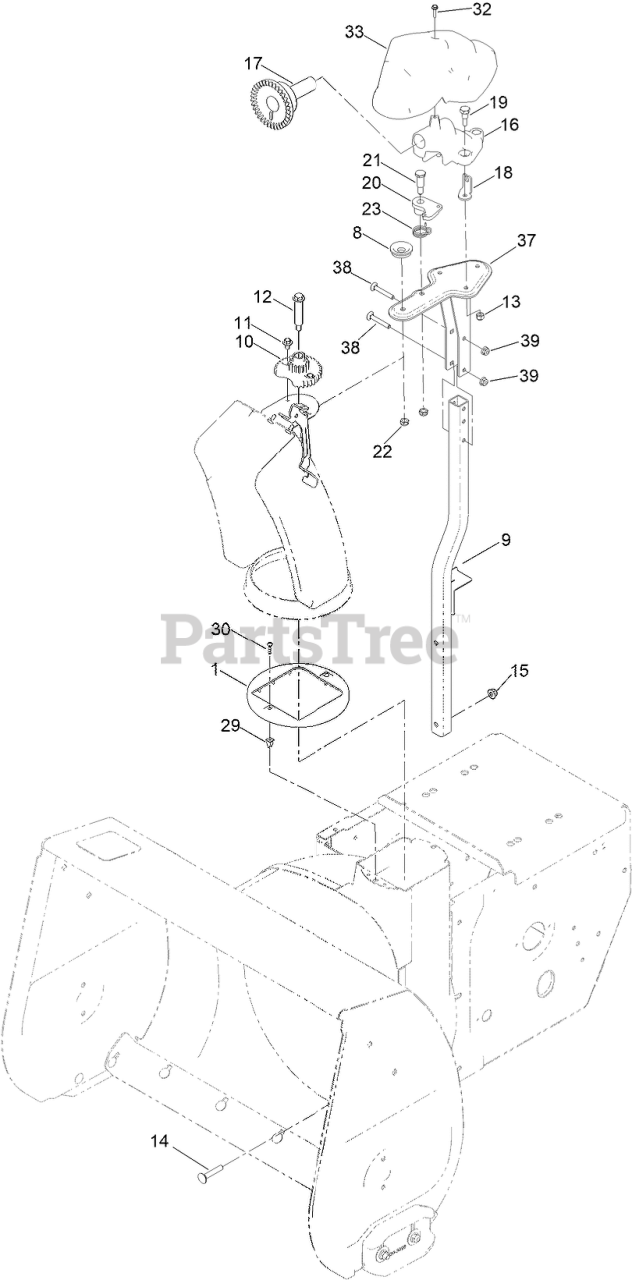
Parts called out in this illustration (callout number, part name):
1	GUIDE-CHUTE
8	SPACER-CHUTE
9	SUPPORT-CHUTE WELD ASM, LOWER
10	GEAR-CHUTE
11	SCREW AND WASHER ASM
12	BOLT-SHOULDER
13	NUT-HEX
14	BOLT-CAR
15	NUT-HF
16	MOUNT-GEAR, FACE
17	GEAR-FACE
18	ANCHOR-CABLE
19	SCREW-SHOULDER
20	LATCH-CHUTE
21	SCREW-SHOULDER, HH
22	NUT-HEX
23	SPRING-TORSION
29	GROMMET-SCREW
30	SCREW-PPH
32	SCREW-PLASTITE, HWH
33	COVER-GEAR, FACE
37	SUPPORT-CHUTE WELD ASM, UPPER
38	BOLT-CARR
39	NUT-FLANGE, NI
